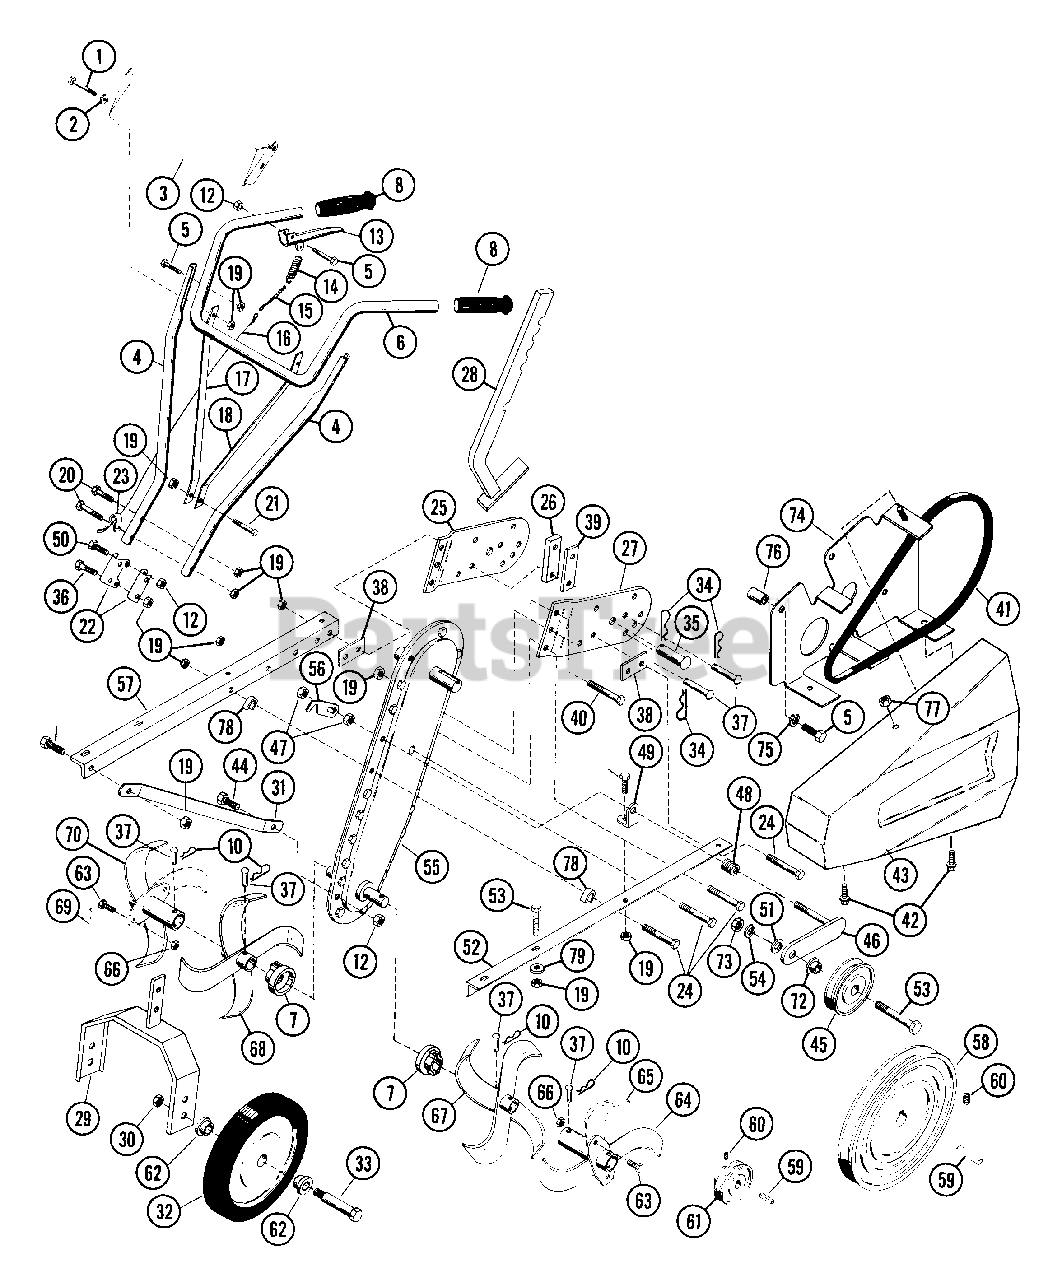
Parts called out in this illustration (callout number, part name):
1	BLT-HEX .25-20X1.75 PL GR2
2	HANDLE BAR WASHER
3	HANDLEBAR PANEL
4	LOWER HANDLE BAR
5	BLT-HEX .25-20X1.50 PL GR5
6	HANDLEBAR
7	DUST CUP
8	GRIP
10	PIN-HAIR INT .08X.38X1.42 YWZC
12	NUT-LK-CTR .250-20 PL
13	CLUTCH HANDLE
14	SG-TENS .092X.69X1.75 WLD 54
17	SUPPORT
18	SUPPORT
19	NUT-LK .312-18 GR A PL
20	BLT-HEX .31-18X3.25 PL GR2
21	BLT-HEX .31-18X2.25 PL GR2
23	CABLE GUID
24	BLT-HEX .31-18X2.50 PL GR2
25	R H WHEEL BRACKET
27	L H WHEEL BRACKET
28	DEPTH BAR
29	WHEEL MTG
30	NUT-LK-JAM-CTR .375-16 PL
31	ENGINE BRACE
33	WHEEL SHOULDER BOLT
34	PIN-HAIR INT .09X.62X2.25
35	PIN-CLEV .494X1.94 YWZC
36	BLT-HEX .31-18X.75 PL GR2
37	CLEVIS PIN
40	BLT-HEX .31-18X1.25 PL GR2
41	V-BELT, 4L-WRAPPED
42	BLT-SERHFWH .25-20X.50 PL
43	BELT COVER
44	BLT-HEX .25-20X1.00 PL GR5
45	IDLER
46	IDLER ARM
47	NUT-HEX .375-16
48	SG-COMP .041X.50X.56 WLD2
49	IDLER ARM
50	BLT-HEX .25-20X.75 PL GR2
51	WSHR-FL-STL .38X.875X.083 PL
52	LH FRAME
53	BLT-HEX .31-18X1.50 PL GR2
54	WSHR-LK .312X.097 PL HVY
55	CHAIN CASE ASSEMBLY
56	LEVER CABL
57	RH FRAME
58	DRIVE SHEAVE
59	KEY-SQ .188X1.0X.188 SAE 8630
60	SCR-SET .32-18X.38 SKHCUPNL OH
61	ENGINE SHEAVE
62	BSHG-FLG .500X.625X.500X.750
63	BLT-HEX .44-14X1.00 GR5
64	L H OUTER TINE SPOOL
65	L H TURBO-TINE
66	NUT-LK-TOP .437-14 GR C PL
67	L H INNER TINE SPOOL
68	R H INNER TINE SPOOL
69	R H TURBO-TINE
70	R H OUTER TINE SPOOL
72	SPCR, BRG .315X.50X.688X.281
73	NUT-HEX .312-18
74	RETAINER
75	WSHR-LK .250X.077 HVY PL
76	SPACER .63 X .28 X .31
77	NUT-LK-FLG .250-20 PL
78	U SPACER
79	WSHR-FL-STL.312X.734X.065PL
